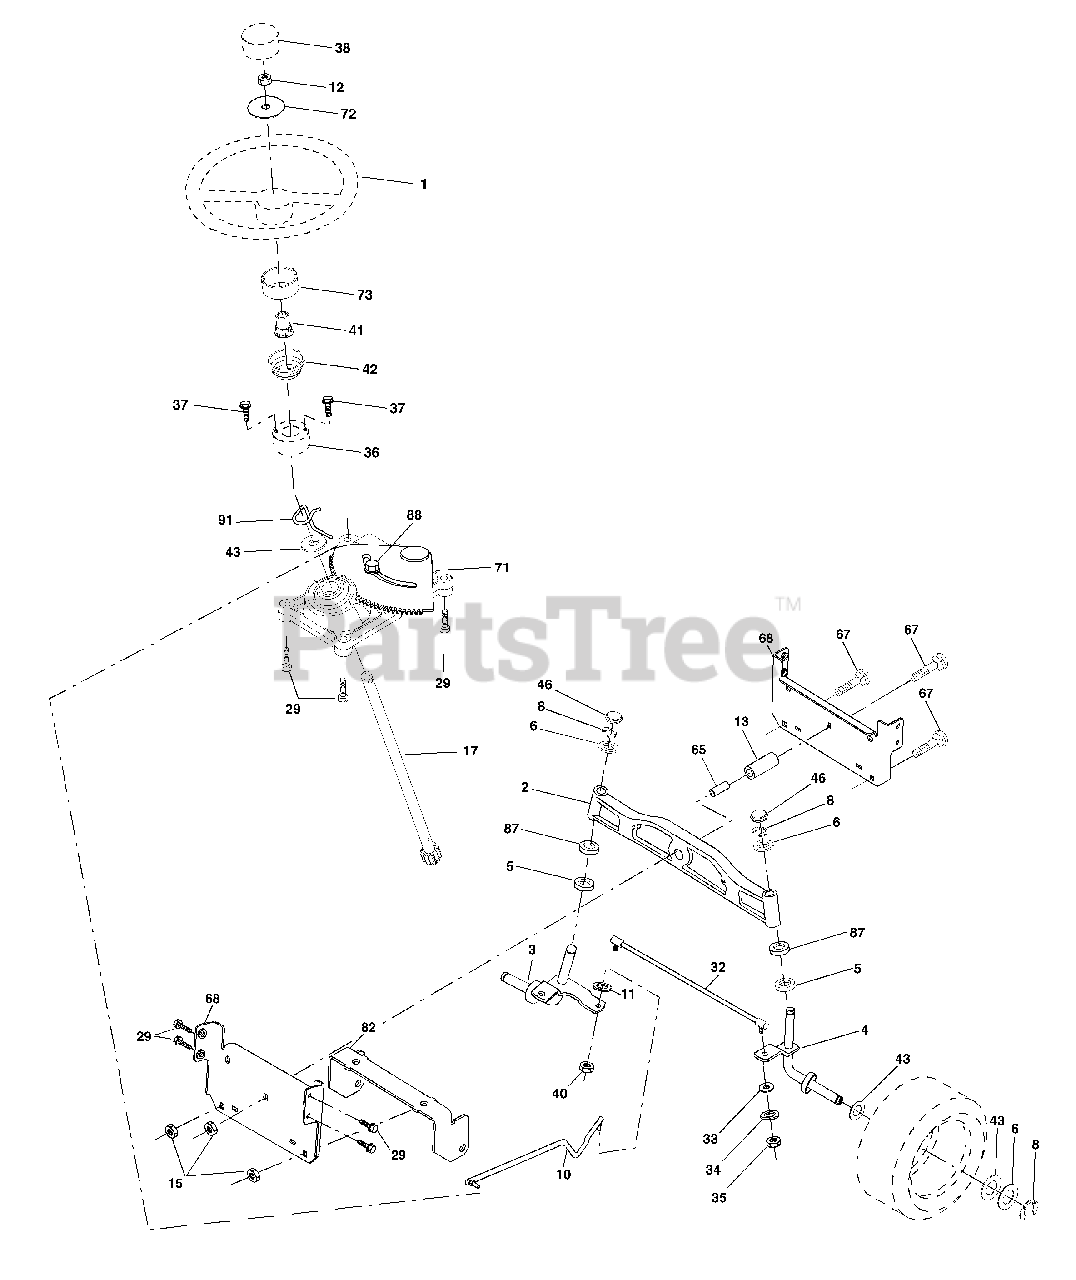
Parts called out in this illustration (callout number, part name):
1	Wheel Steering
2	Axle Cast Lt Machined
3	Spindle Asm LH
4	Spindle Asm RH
5	Bearing Race Thrust Harden
6	Washer 25/32 X 1-5/8 X 16 Ga
8	Ring Klip #t5304-75
10	Link Drag
11	Washer Lock Hvy Hlcl Spr 3/8
12	Nut Hex Jam Toplock 1/2-20 UNF
13	Spacer Brg Axle Front
15	Nut Hex Flange Lock
17	Shaft Asm Strg
29	Screw 3/8-16 x 3/4
32	Rod Tie
33	Washer 11/32 x 3/4 x 16 Ga.
34	Washer Lock Hry Hlcl Spr 5/16
35	Nut Crownlock 5/16 - 24 UNF
36	Bushing Strg
37	Screw TT #32.5 x 5 x 3/8 Flange
38	Cap Wheel Steer
40	Nut Lock Center 3/8-24 Unf
41	Adaptor Wheel Strg
42	Boot Steering
43	Washer 25/32 X 1 1/4 X 16 Ga
46	Cap Spindle Fr Top Blk
65	Spacer Brace Axle
67	Bolt Rdhd Sqn 3/8-16 x 2-1/4
68	Brace, Axle
71	Steering Asm.
72	Washer 9/16 ID x 1/20 OD 11 Ga.
73	Extension Steering
82	Bracket Susp Chassis Front
87	Washer Flat .781 x 1-1/2 x .14
88	Bolt Shoulder 7/16-20 Unc
91	Clip
